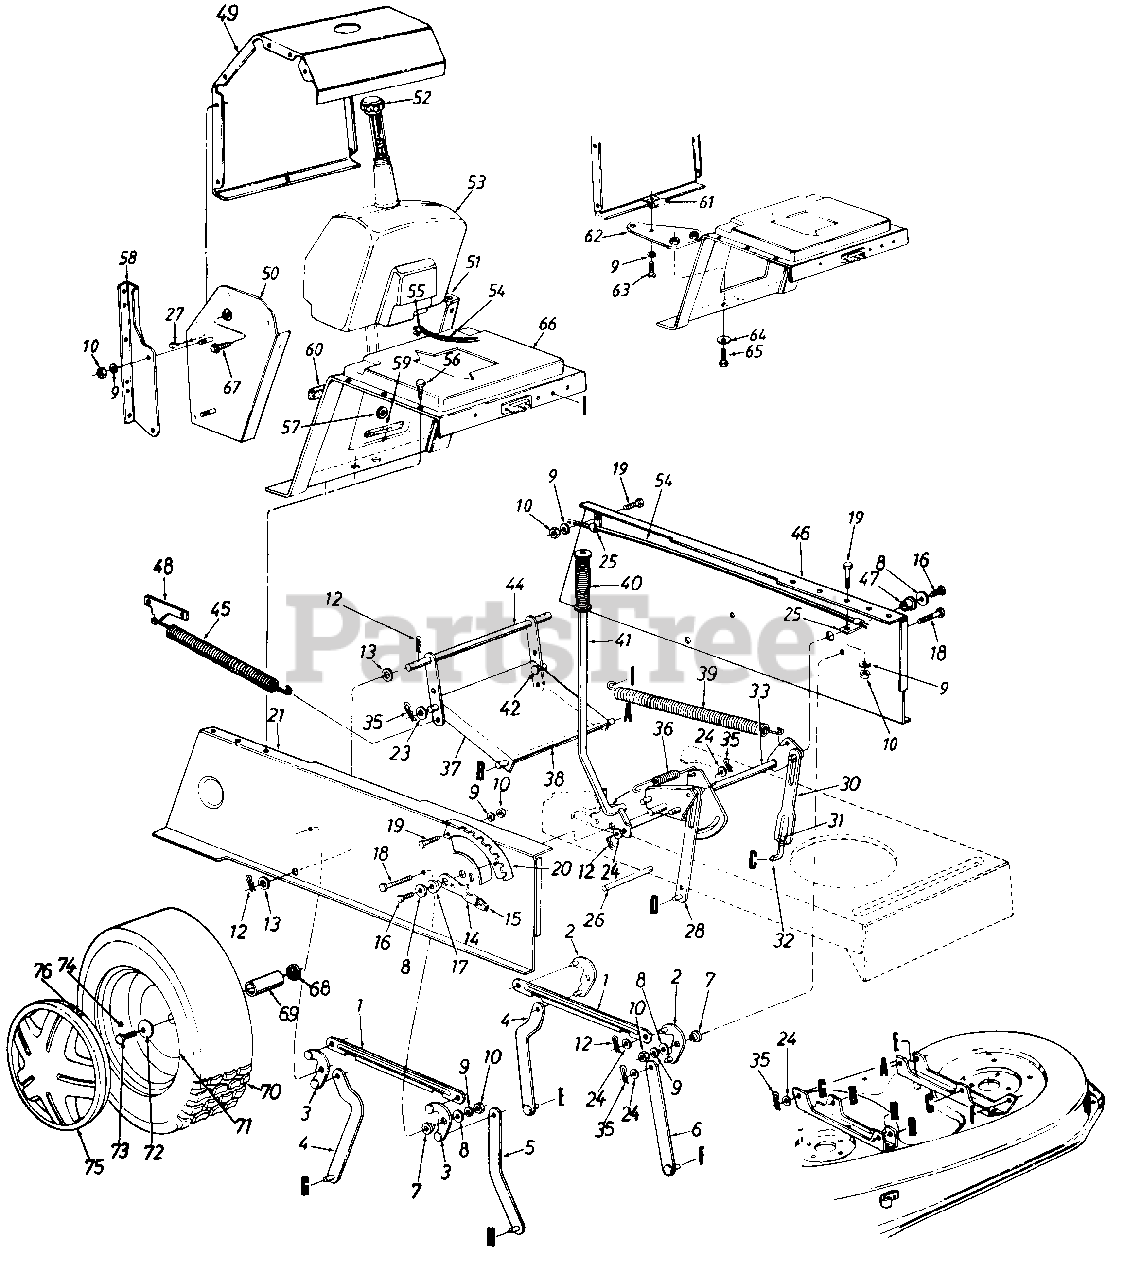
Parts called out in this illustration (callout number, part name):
1	Connecting Rod
2	Pivot Link Ass'y. L.H.
3	Pivot Link Ass'y. R.H.
7	Shld. Spacer .3/8" I.D.
8	Fl-Wash. .344" I.D. x 1.125"
9	L-Wash. 5/16" I.D.
10	Hex Nut 5/16-18 Thd.
12	Cotter Pin 1/8" Dia.
13	Fl-Wash. 635" I.D. x 1.0" O.D.
14	Deck Lift Down Stop
15	Knob
16	Hex Wash. TT-Tap Scr. 5/16-18 x .75" Lg.
17	Flange Brg. .63" I.D.
18	Hex Wash. TT-Tap Scr. 5/16-18 x .875" Lg.
19	Hex Bolt 5/16-18 x .75" Lg.
20	Index Brkt.
21	Upper Frame R.H.
23	Fl-Wash. .385" I.D. x .87" O.D.
24	Fl-Wash. .531" I.D. x .93" O.D.
25	Clamp
26	Running Board Rod
27	Truss Mach. Scr. #10 x .5" Lg.
31	Hex Nut 1/2-20 Thd. (Grade 5)
32	Lift Link Adjuster
33	Lift Shaft Ass'y.
35	Inter. Cotter Pin 3/8" Dia.
36	Extension Spring
37	Stabilizer Bracket
38	Shaft 1/2" Dia. x 10.28" Lg.
39	Extension Spring
40	Grip
41	Deck Lift Handle Ass'y.
42	Weld Pin .375" Dia. x 1.25" Lg.
44	Stabilizer Shaft Ass'y.
45	Extension Spring 7.58" Lg.
46	Upper Frame L.H.
47	Flange Brg. .632" I.D.
48	Spring Retainer Brkt.
49	Gas Tank Housing
50	Side Panel Ass'y. R.H.
53	Gas Tank
54	Fuel Line
55	Hose Clamp
56	Hex Wash. AB-Tap 5/16 x .75" Lg.
57	Rubber Grommet
58	Mtg. Brkt. R.H.
59	Trim Strip
60	Foam Strip
61	Speed Nut
62	Hitch Bar Ass'y.
63	Hex Bolt 5/16-18 x 1.0" Lg. (Grade 5)
64	Bell-Wash. .38" I.D. x .88"
65	Hex Wash. Tap Scr. 3/8-16 x .75" Lg.
66	Hitch Plate
67	Hex Wash. Hd. Tap Scr. 1/4-20 x.38" Lg.
68	Fl-Wash. .76" I.D. x 1.49" O.D.
69	Sleeve .75" I.D. x 1.0" O.D.
72	Bell-Wash. .345" I.D. x .88"
73	Hex L-Bolt 5/16-24 x 75" Lg.
74	Air Valve
75	Hub Cap
76	Spring Clip
